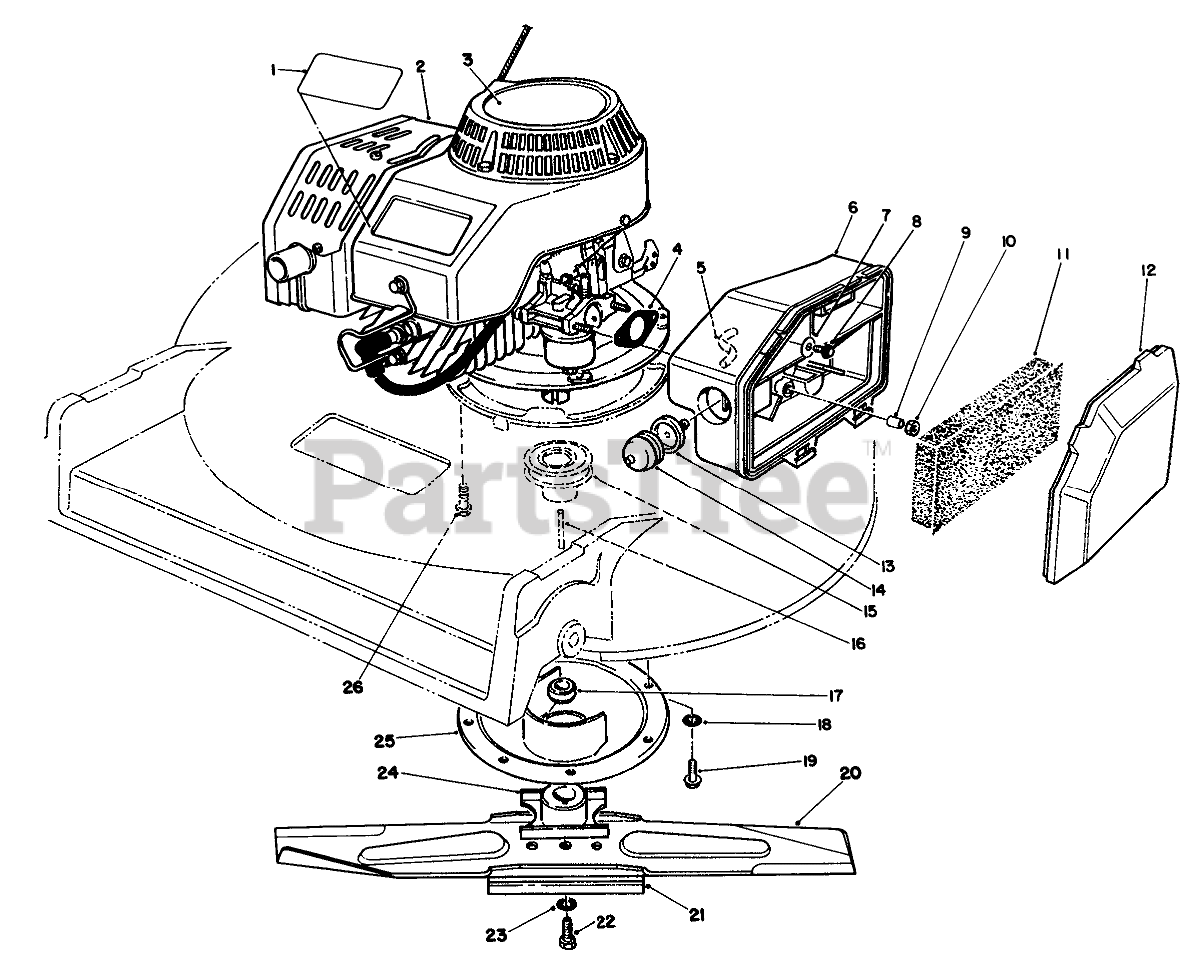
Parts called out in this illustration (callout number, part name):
1	DECAL - PROLINE
2	ENGINE ASM
3	DECAL-2 CYC RECOIL COMM
4	GASKET-AIR CLEANER
5	HOSE-PRIMER
6	BODY-AIR CLEANER
7	WASHER-FLAT
8	SCREW-HH
9	SPACER
11	ELEMENT-AIR CLEANER
12	COVER-AIR CLEANER
13	BODY-PRIMER
14	BULB-PRIMER
15	PULLEY-DRIVER
16	KEY-SQUARE
17	SPACER-BLADE RETAINER
18	WASHER-LOCK, INTERNAL
19	SCREW-HWHTF
20	Blade (Incl. Ref. #21)
21	Stiffener
22	SCREW-BLADE
23	WASHER-LOCK
24	RETAINER-BLADE
25	PROTECTOR-CRANKSHAFT
26	SCREW-HHF
